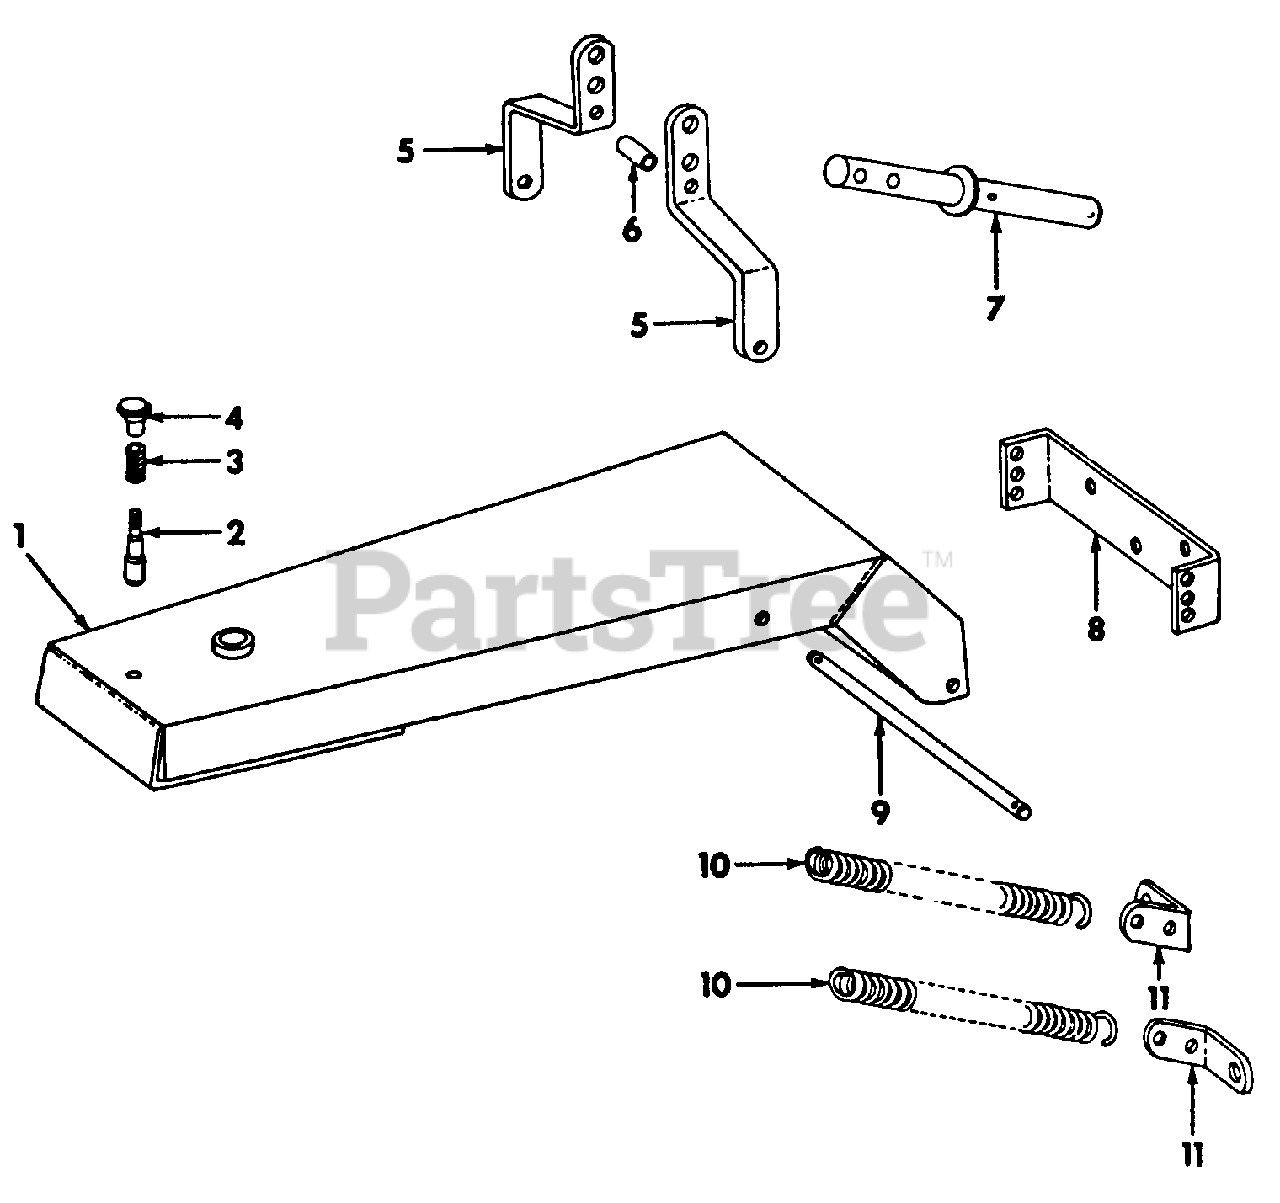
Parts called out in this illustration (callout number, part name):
1	Frame Assy, Main
3	Spring, Pivot Pin
4	Knob, Pivot Pin
5	Bracket, Hitch
6	Spacer, Lift Link
7	Pin Assy, Hitch Lift
8	Channel, Hitch Mount
10	Spring, Lifting
11	Angle, Spring Attaching
